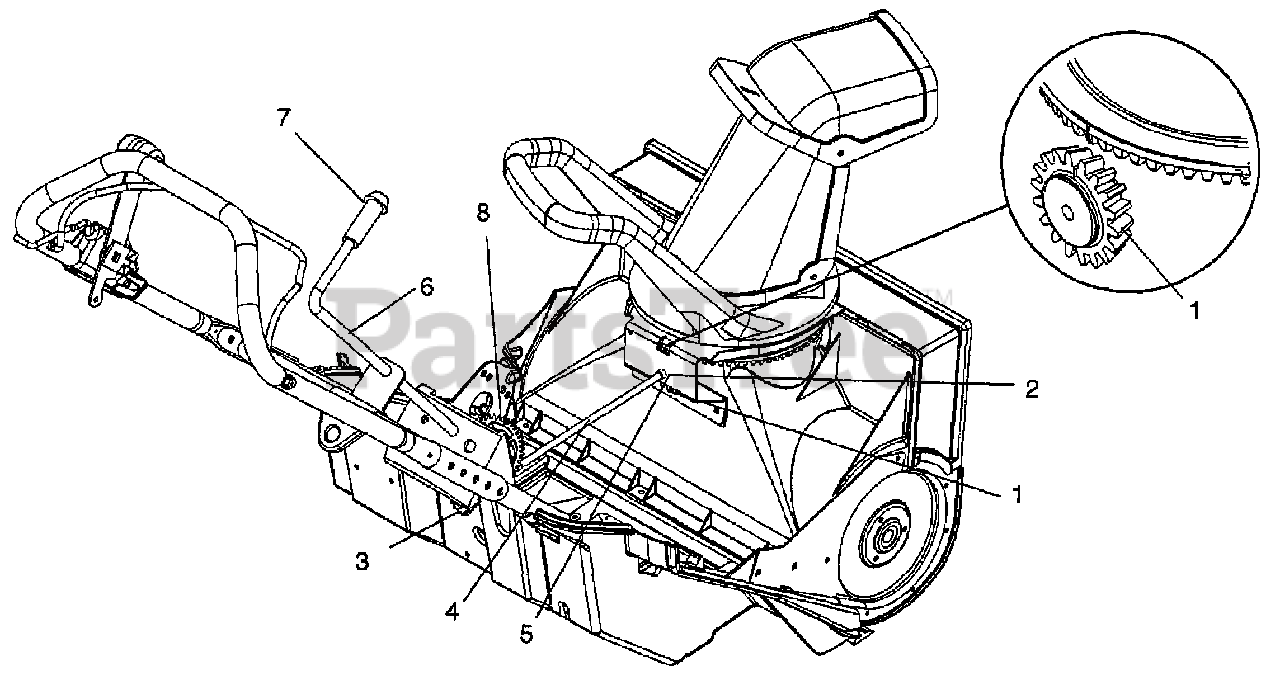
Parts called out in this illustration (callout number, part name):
1	PINION-DISCHARGE CHUTE 18T
2	BSHG-FLG .325X.444X.440X.560
3	PINION-CRANK TRANSFER 12T
4	SHAFT CHUTE CRANK TRANSFER
5	PIN-HAIR INT .08X.38X1.42 YWZC
6	CRANK-CHUTE ASSY
8	GEAR-CRANK TRANSFER 48T
9	BSHG-SLV .510X.753X2.00
10	@PIN-CTR .16X1.25 EXTPRSQCT YZ
